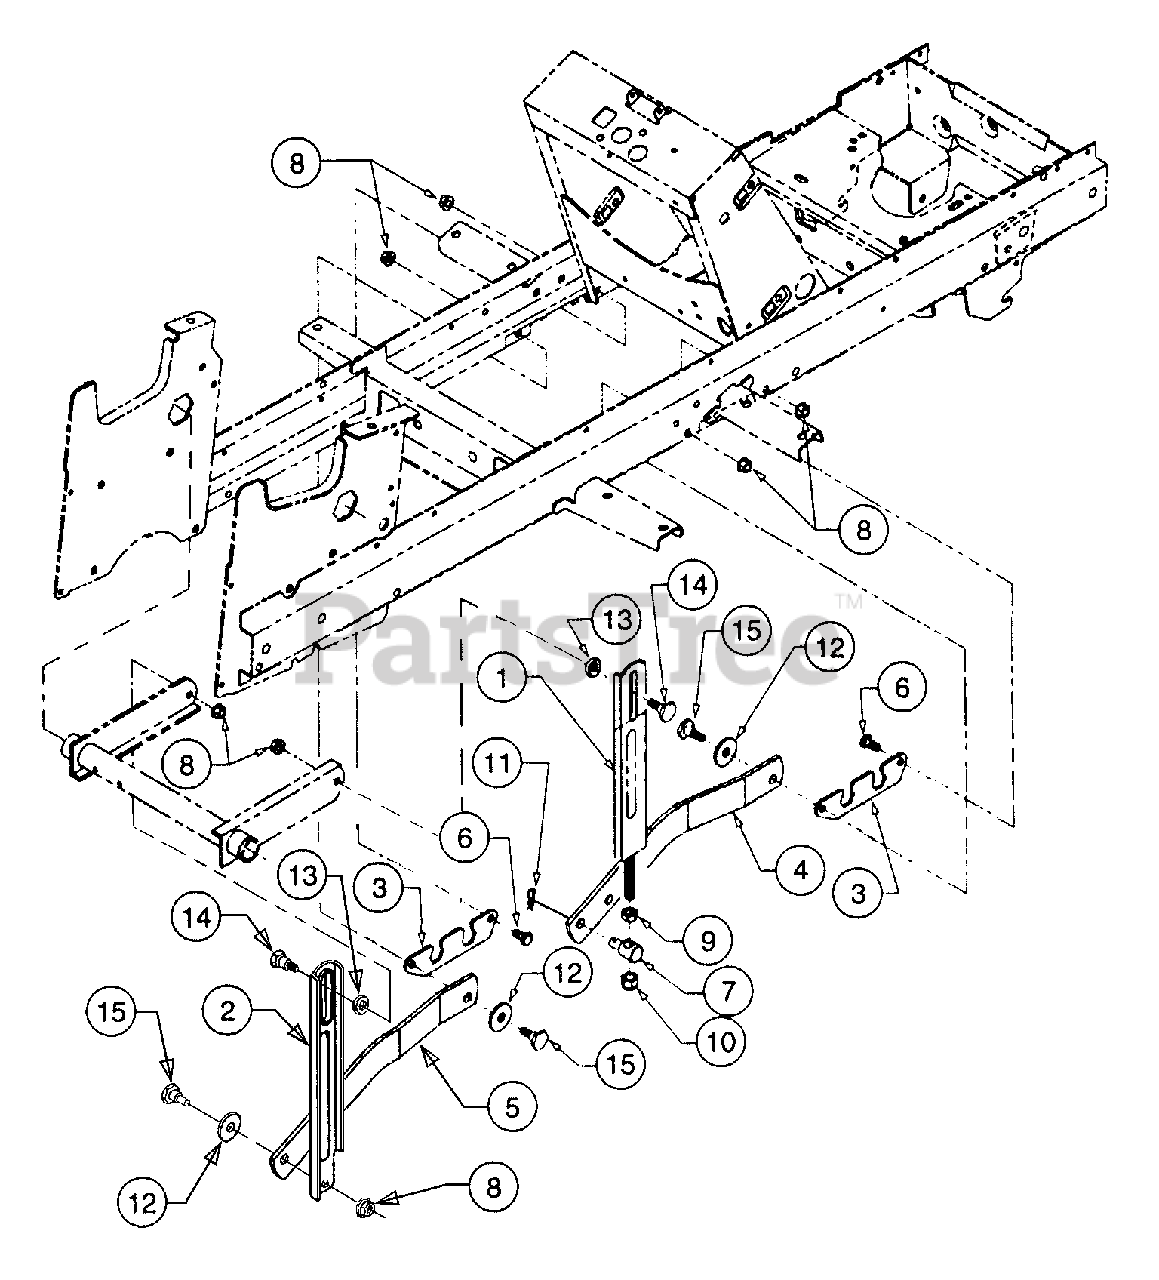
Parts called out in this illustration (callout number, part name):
7	Ferrule, Adjustment
8	Nut, Hex Flange Lock, 3/8-16
9	Nut, Hex Jam, 1/2-13 GR5
10	Nut, Hex Insert Lock, 1/2-13
11	Pin, Internal Cotter
12	Washer, Flat, .5 x 1.5 x .15
13	Washer, Flat, .531 x .875 x .15
14	Bolt, Shoulder
15	Bolt, Shoulder
